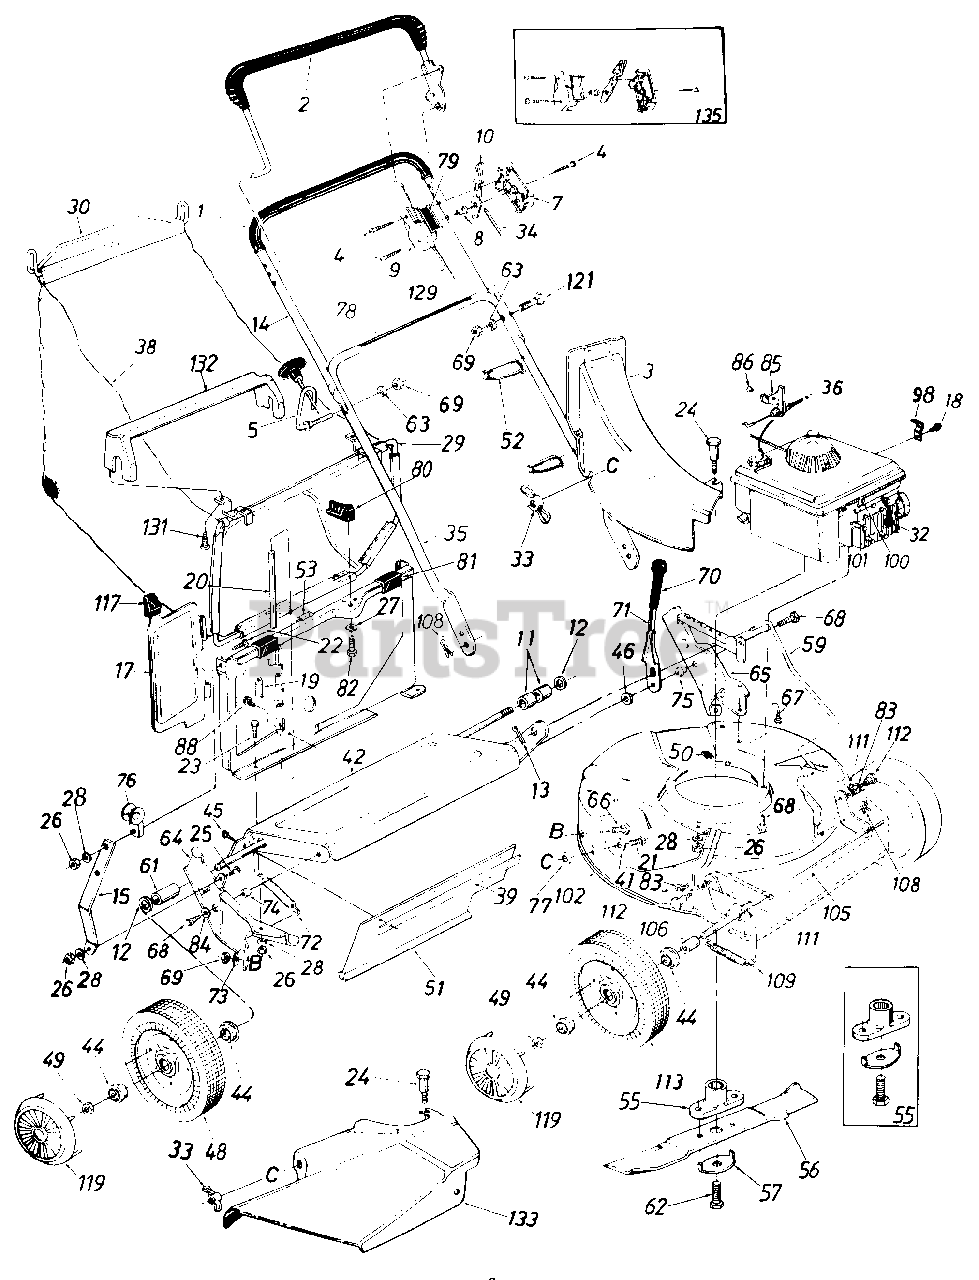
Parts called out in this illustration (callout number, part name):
1	Foam Grip
2	Control Handle Ass'y.-L.H.
3	Top Discharge Chute Ass y
4	Truss Mach. Scr. #12 x 1.50" Lg.
5	Rope Guide Bolt
7	Control Panel Half
8	Control Disc Pin
9	Clutch Panel Half
10	Throttle Control Lever
11	Spacer 526" I.D. x .690" O.D. x .640" Lg.
12	Fl-Wash. .510" I.D. x .75"
13	ICotter Pin 3/32" Dia. x .75"
14	Upper Handle-Chrome
15	Panel Support Brkt.
15	Top Catcher Panel Ass y.
17	Top Discharge Door
18	IHex B-Tap Scr. #10 x .38"
19	Torsion Spring
20	Pivot Pin
21	Carriage Bolt 1/4-20 x .62"
22	Truss Mach. Scr. 1/4-20 x 75 Lg
23	Hex Bolt 1/4-20 x .50" Lg.
24	Shoulder Bolt .312 Dia. x .18 Lg. Special
25	Hex Bolt 1/4-20 x .62" Lg.
26	Hex Nut 1/4-20 Thd.
27	Spring Wash. .32" I.D.
28	L-Wash. 1/4" I.D.
29	Front Grass Catcher Framet
30	Upper Bag Handlet
32	Spark Plug Insulator
33	Wing Nut w/Washer
34	Throttle Control Wire-58"
36	Engine
38	21" Top Discharge Grass Bag-Black
38	21" Top Discharge Grass Bag-Grey
39	Retaining Strip
41	Fl-Wash. .344" I.D. x .62"
42	Rear Axle Ass'y.
44	Flange Ball Bearing 1/2" I.D.
45	Hex AB-Tap Scr. '/4 x .62"
46	Fl-Wash. .38" I.D. x 1.0"
48	Wheel Ass'y. (7 x 1.75)
48	Wheel Ass'y. (8 x 1.75)
48	Wheel Ass'y. (7 x 2)
48	Wheel Ass'y. (8 x 2)
49	Hex L-Nut 1/2-20 Thd.
51	Rear Flap 3.75" x 17.30" Lg.
52	Cable Tie
53	Foam Strip 1" Lg.
55	Blade Adapter Kit
56	21" Blade
57	Blade Bell-Wash. .44" I.D. x 2.38"
59	Height Adj. Rod. 19.42" Lg.
61	Sleeve.526" I.D 0 x.69"
62	Hex Bolt 3/8-24 x 1.5" Lg.
63	L-Wash. 5/16" I.D.
64	R.H. Handle Wheel Brkt. Ass 'y .
65	L.H. Handle Wheel Brkt. Ass'y.
66	Carriage Bolt 5/16-18 x .62"'
67	Hex Wash. Hd. B-Tap Scr. 5/16-18
68	Hex Wash. Hd. TT-Tap Scr. 3/8-16
69	Hex Nut 5/16-18 Thd.'
71	Height Adj. Lever
72	Extension Spring 3.8" Lg.
73	Bell-Wash. 5/16" I.D.
74	Spacer .385" I.D. x .502" O.D. x .270" Lg.
75	Shld. Spacer .500" Dia.
76	Rope Guide
77	Bolt Retainer 1/4 x 50" O.D.
78	Instruction Label
79	Control Label
80	Grass Catcher Locking Knob
81	Panel Clip
82	Hex Tap Scr. 1/4-20 x .75" Lg.
83	Flanged Nyliner Brg.
84	Fl-Wash. .531" I.D. x 1.25"
85	Cable Bracket
86	Pop Rivet .156" Dia.
88	Hex B-Tap Scr. #10 x .38"
98	Cable Clamp
100	Hex B-Tap Scr. #10 x .62"
101	Cable Clamp
102	21" Deck Ass'y.
105	Front Axle Ass'y.
106	Sleeve .526" I.D. x .690" O.D. x .880" Lg.
108	Intern. Cotter Pin 5/16" Dia.
109	Extension Spring 3.2" Lg.
111	Intern. L-Wash. 3/8 I.D.
112	Shld. Bolt .575" Dia. x .42"
113	Wheel Ass'y. (7 x 1.75)
113	Wheel Ass'y. (8 x 1.75)
113	Wheel Ass'y. (7 x 2)
113	Wheel Ass'y. (8 x 2)
117	Door Grip
119	Hub Cap (7 x 1.75, 8 x 1.75)
119	Hub Cap (7 x 2, 8 x 2)
121	CuNed Carr. Bolt 5/16-18 x 1.38" Lg.
129	Control Cable-46" Lg.
131	Hex AB-Tap Scr. #12 x 1.25"
132	Bag Handle
133	Side Chute Deflector Ass'y.
135	Kit-Control Housing Comp.
